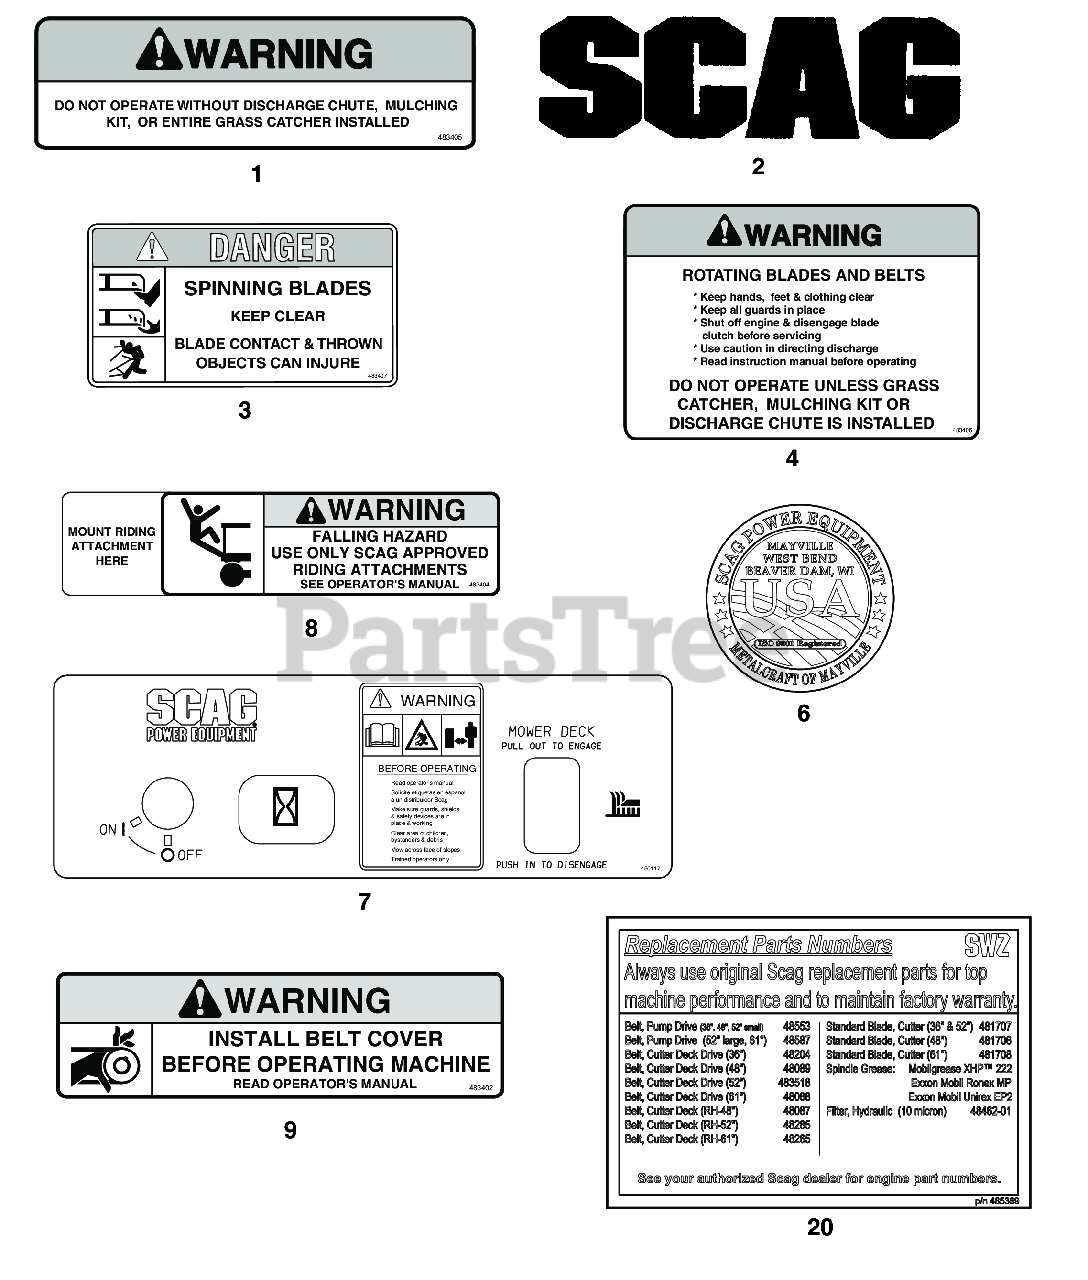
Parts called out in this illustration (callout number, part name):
1	Decal, Warning-Discharge
2	Decal, Scag Logo ( Cutter Deck)
3	Decal, Danger-Spinning Blades
4	Decal, Warning - Rotating Blades
6	Decal, Metalcraft - USA
7	Decal, Instrument Panel - Rear
8	Decal, Sulky Attachment
9	Decal, Warning - Belt Cover
20	Decal, SWZ Replacement Parts
